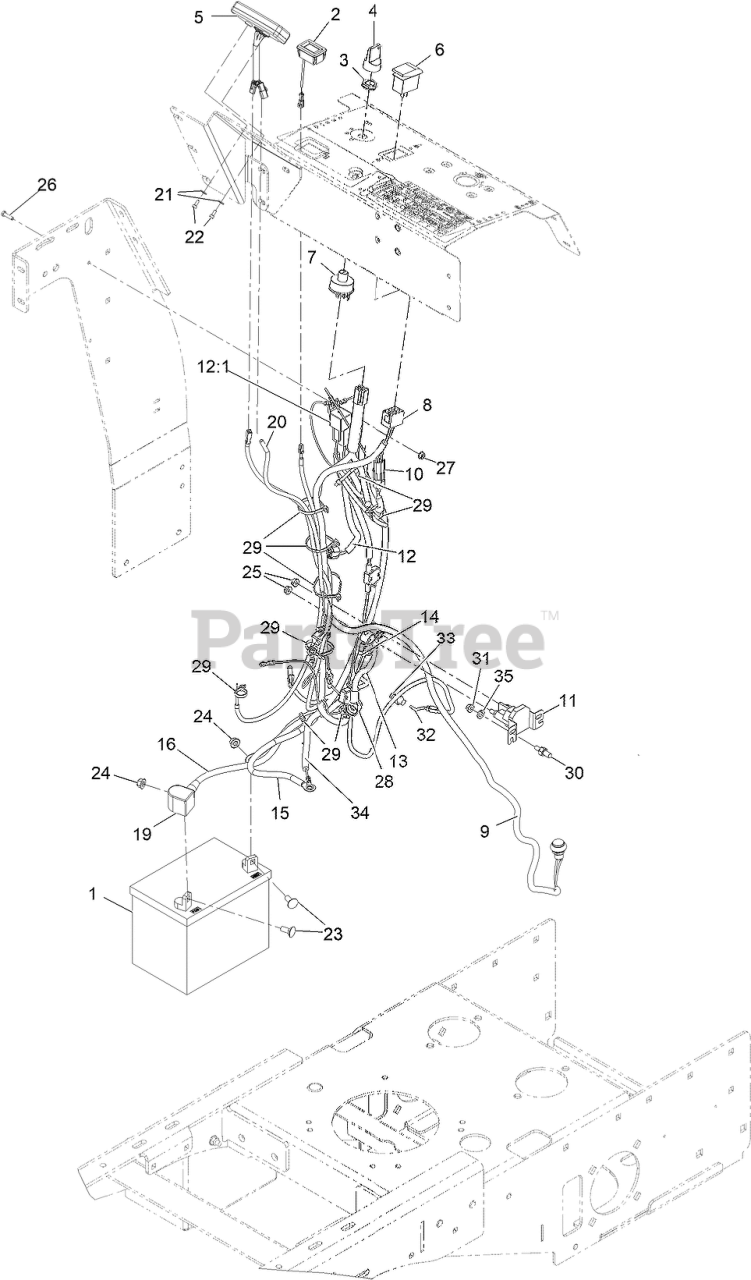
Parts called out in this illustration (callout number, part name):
1	Battery (340 CCA, Wet)
2	METER-TACH/HOUR
3	NUT-SWITCH, KEY
4	KEYS-IGNITION (SPARE PAIR
4	KEY-UMBRELLA
5	HEAD ONLY, STRIKER
6	SWITCH-ROCKER
7	SWITCH-IGNITION
8	CONNECTOR-CARLING, 8F
9	Switch-Push Button
10	Connector-Wp,2M
11	Solenoid-Starter
12	Harness, Main
12:1	RELAY-MINI ISO PWR, 5M
13	Battery (340 CCA, Wet)
14	Wire-Solenoid
15	CABLE-GROUND
16	CABLE-POSITIVE
19	Insulator-Battery
20	HARNESS-STRIKER
21	WASHER-FLAT
22	SCREW-HSH
23	SCREW-CARR
24	Nut-Hex Flange
26	SCREW-HH
27	Nut-Hex Flange
28	INSULATOR-SOLENOID
29	TIE-CABLE
30	STUD-ENGINE
31	Nut-Hex Flange
32	Cable-Trail Tech, Sensor
33	MAGNET, SPEEDOMETER
34	HARNESS-WIRE, JUMPER
35	WASHER-LOCK
